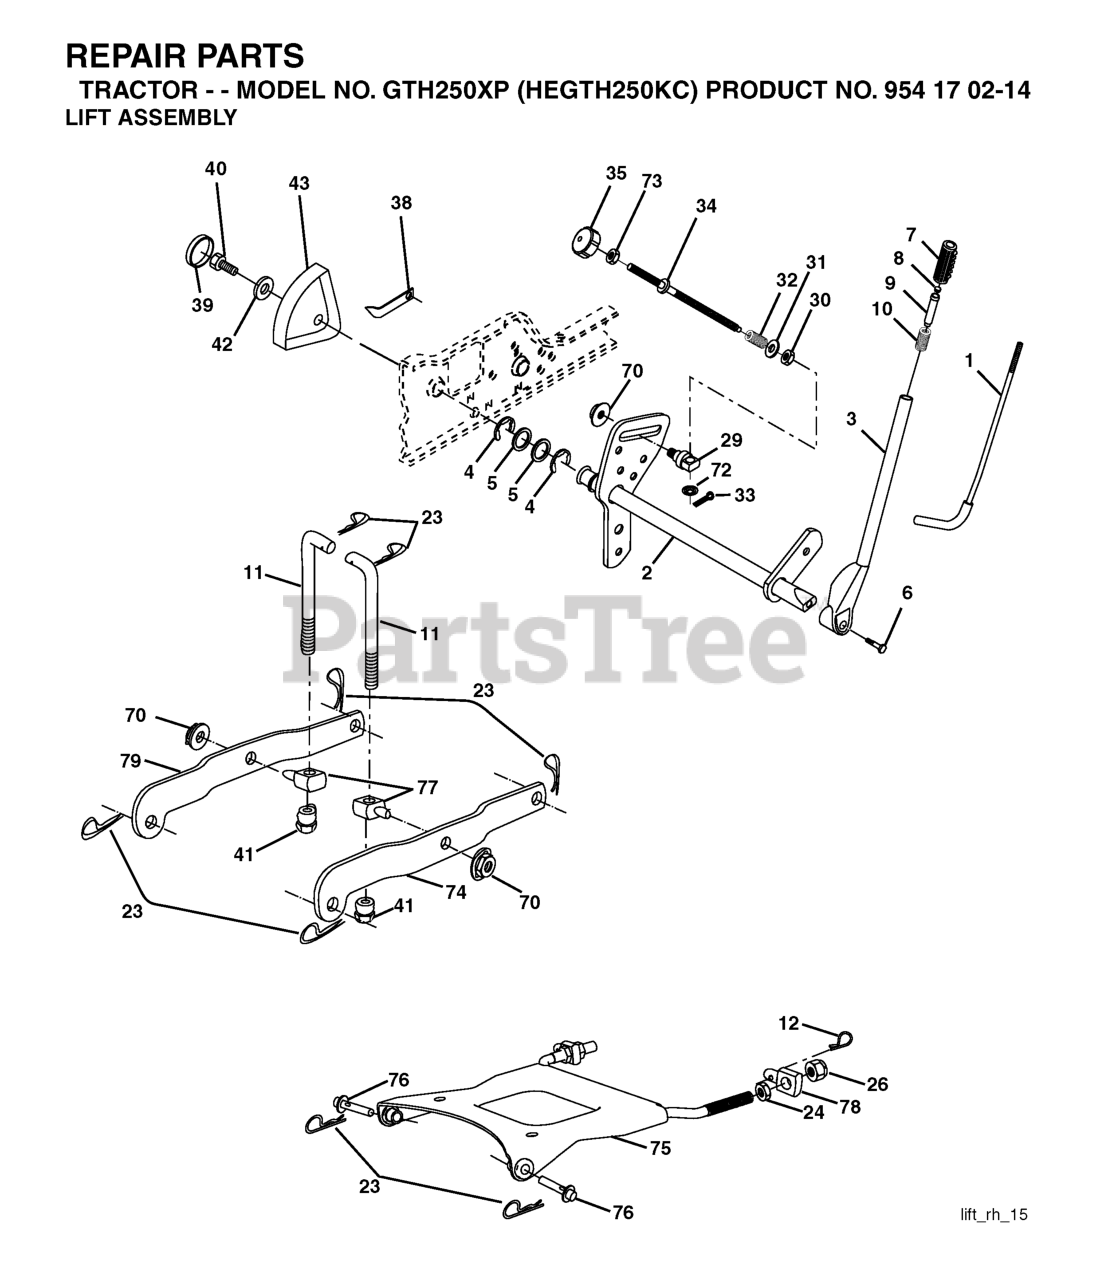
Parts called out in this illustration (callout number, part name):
1	LEVER ROD LT
2	SHAFT ASM., LIFT VGT
3	LEVER ASSY-LIFT RH
5	Washer 29/32 x 1 - 1/4 x 16 Ga.
6	Bolt, Fin Hex 3/8-16 x 1-1/12
7	GRIP HANDLE
8	PLUNGER BUT KIT
9	PLUNGER BUT KIT
10	SPRING 0.620D X 2.125
11	LIFT LINK
12	SPRING RETAINER
23	RETAINER-SPRNG RB
24	NUT.HEX.JAM.1/2-13
26	NUT LTV
32	SPRING.COMP.INF.H
33	COTTER PIN
34	ROD.LIFT.ADJUSTABLE
35	KNOB INF 3/8-16
38	POINTER, HEIGHT INDICATOR(2 2)
40	SCREW 5/16-18X1
41	NUT, LIFT LINK 7/16-20
43	HEIGHT INDICATOR
70	NUT
72	NUT PUSH M
73	NUT
74	ARM SUSP REAR RH
75	PLATE ASM SUSP FRONT
76	PIN.FLANGE
79	ARM SUSP. REAR LH
